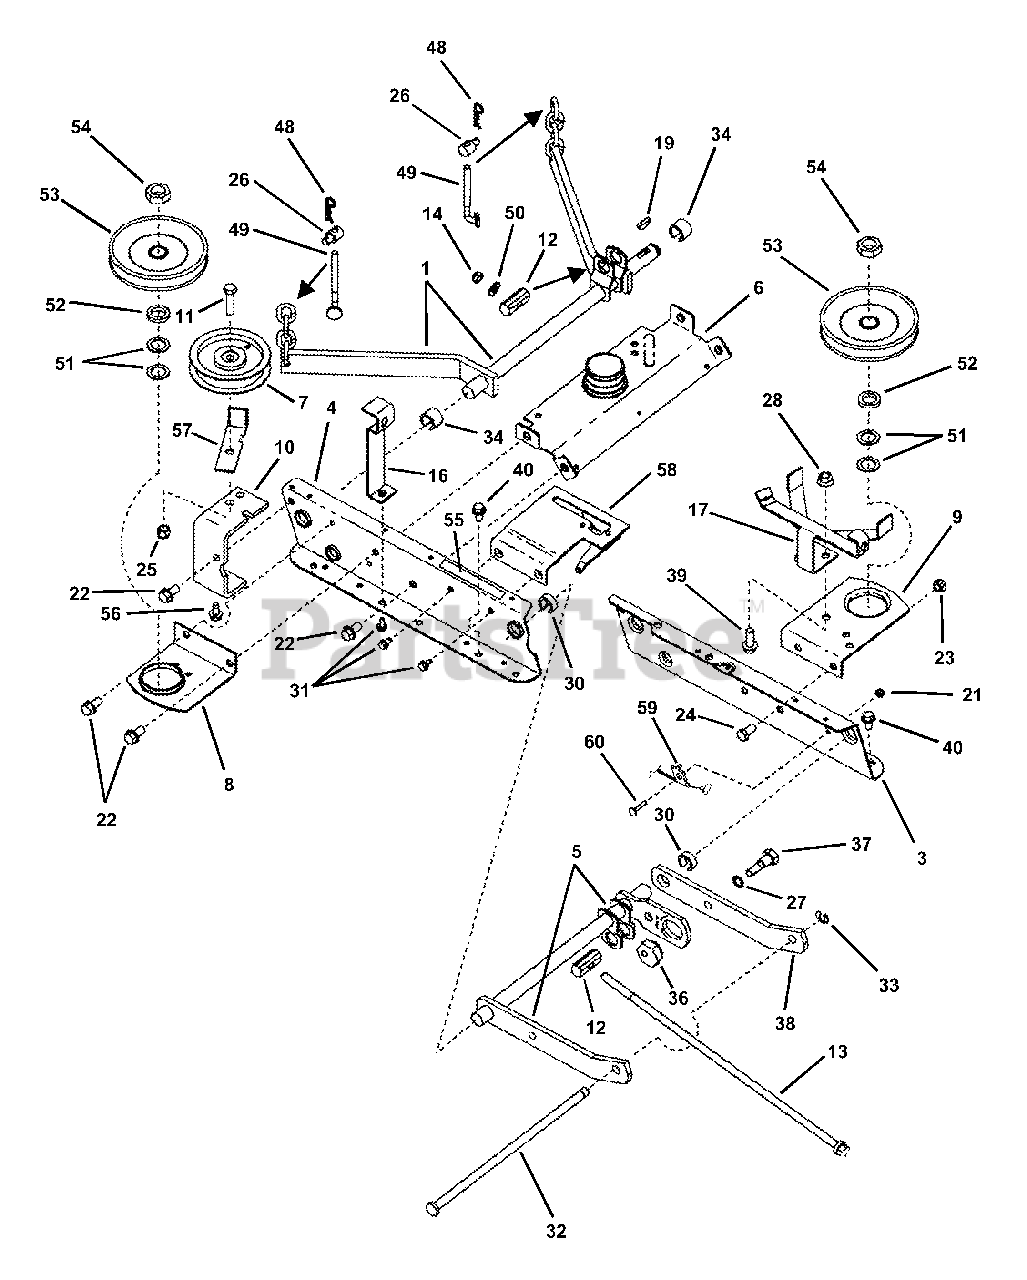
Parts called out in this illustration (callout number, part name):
1	ASSEMBLY, Rear Lift Arm
3	RAIL, Left Half
4	RAIL, Right Half
5	STRUCTURE, Front Lift Arm
6	BRACE, Weldment
7	IDLER, 4-1/8" Flat
8	SPINDLE, Brace (Right)
9	SPINDLE, Brace (Left)
10	BRACE/IDLER Mtg. Bracket
11	SCREW, 3/8-16 x 1-1/2" Hex
12	PIVOT
13	ROD, Leveling
14	NUT, 3/8-24 Hex Top Lock
16	GUIDE, Belt (Rod)
17	GUIDE, Belt, 42" RER (Weldm't)
19	KEY, 3/16 x 7/8" Woodruff
21	NUT, #10-24 Hex Nyloc
22	SCREW, 3/8-16 x 3/4" Tap
23	NUT, 3/8-16 Hex Center Lock
24	SCREW, 3/8-16 x 3/4" Hex
25	NUT, 3/8-16 Hex Nyloc
26	SWIVEL, Adjustable
27	WASHER, 3/8 Int. Tooth Lock
28	NUT, 3/8-24 Hex Lock
30	RING, Red
31	SCREW, 5/16-18 x 1/2" Tap
32	SUPPORT, Rod
33	RING, Retaining
34	RING, Blue
36	ECCENTRIC, Leveling
37	BOLT, 3/8-24 x 3/4" Shoulder
38	ARM, Front Lift (Left Side)
39	BOLT, 3/8-16 x 1" Hex Flange Lock, Grade 5
40	BOLT, 5/16-18 x 5/8" Hex
48	HAIRPIN, 3/32 x 1-1/2"
49	ADJUSTER, Chain
50	WASHER, 3/8" Flat
51	WASHER, 3/4 Flat
52	SPACER, 3/4" I.D.
53	PULLEY, 5" O.D.
54	NUT, 3/4-16 Hex Jam Lock
55	DECAL, Blade ON/OFF
56	BOLT, 5/16-18 x 5/8" Self-Tap
57	GUIDE, Belt
58	ASSEMBLY, Clutch Plate
59	CABLE, No-Reverse-In-Mow
60	BOLT, #10-24 x 1" Flat Head Square Neck
